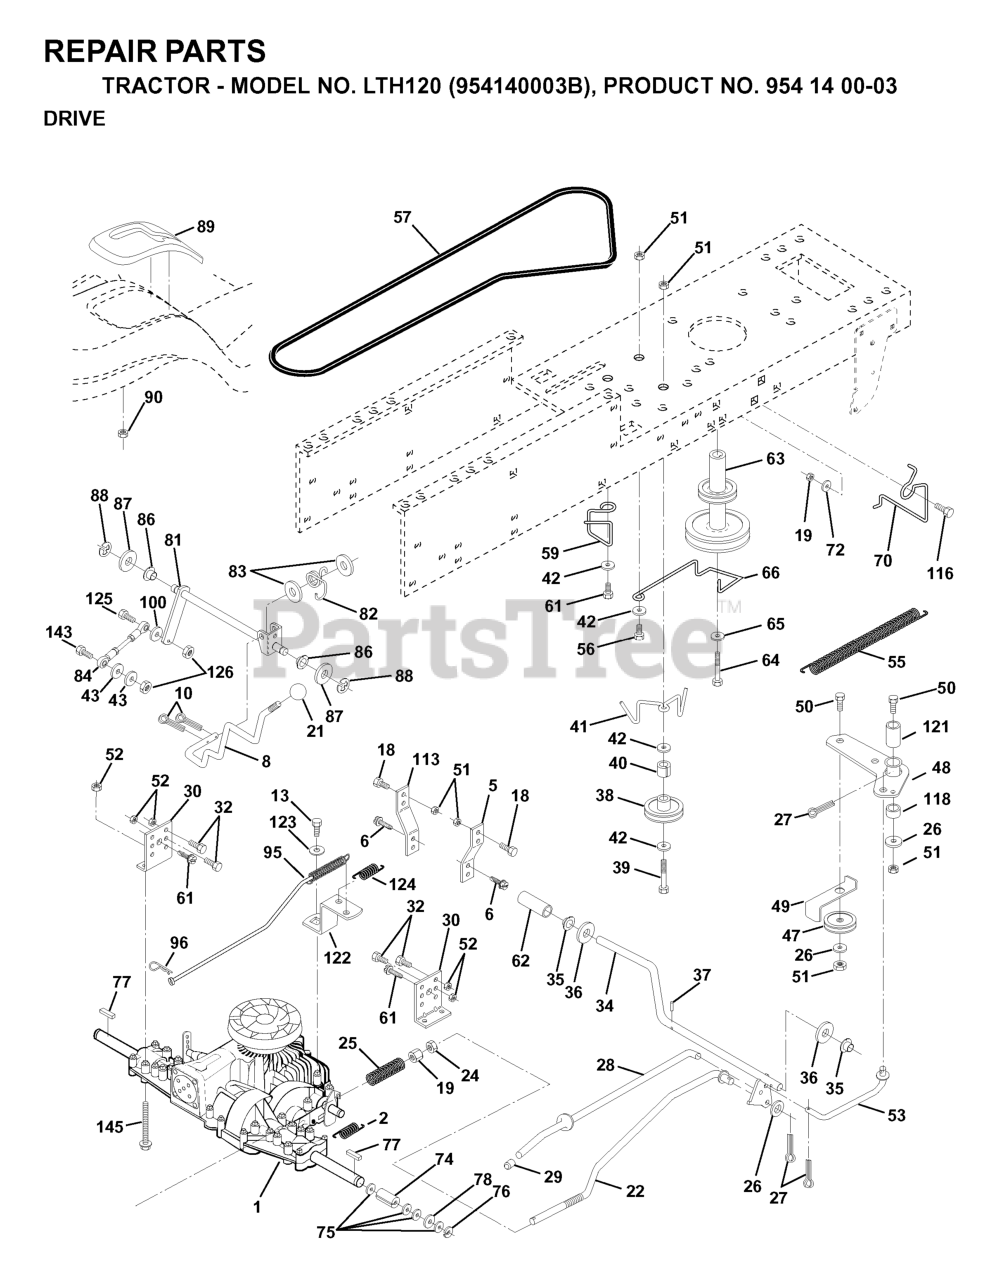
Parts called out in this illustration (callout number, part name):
2	SPRING,BRAKE RETURN
5	STRAP TORQUE
6	SCREW.THDROL.5/16-18X3/4.TTY
8	ROD SHIFT FENDER
10	PIN COTTER
13	BOLT 1/4-28X3/4
15	BOLT HEX 5/16-18 GR 5
19	NUT
21	KNOB T (1/2-HOLE)
24	NUT
25	SPRING ROD LT
26	WASHER
27	COTTER PIN
28	ROD BRAKE PARK LT
29	PLUNGER CAP
30	BRACKET TRANSAXLE
32	BOLT
34	SHAFT, FOOT PEDAL
35	BEARING.NYLON
37	DRIVE PIN
38	PULLEY.IDLER.FLAT
41	KEEPER, BELT IDLER
42	WASHER
47	IDLER PULLEY
48	BELLCRANK ASSEMBLY
49	RETAIN BELT
50	BOLT
52	LOCKNUT
53	LINK, CLUTCH LT
55	SPRING, RETURN LT
57	RP.V-BELT
59	KEEPER CENTER SPAN
61	SCREW
62	PEDAL COVER T
63	PULLEY.ENG.CL.MECH.SLVR.LT/YT
64	BOLT
65	LOCKWASHER
66	KEEPER BELT ENGINE
70	KEEPER BELT ENG
72	WASHER
77	SQUARE KEY
82	SPRING,TORSION
83	WASHER
86	BUSHING.STEERING.ROD LTB-WSL
89	CONSOLE SHIFT
90	NUT.PUSH.3/16
95	ROD ASM BYPASS PVST
96	RETAINER M
100	WASHER M
113	STRAP TORQUE LH LT
116	BOLT
118	SPACER BELLCRANK
121	NYLINER CLUTCHING
122	PLATE BYPASS PVST
124	RETURN SPRING
125	BOLT.FIN.HEX.5/16-18UNC X 1.00
143	BOLT.5/16-18X1-1/4 FULL.THREAD
